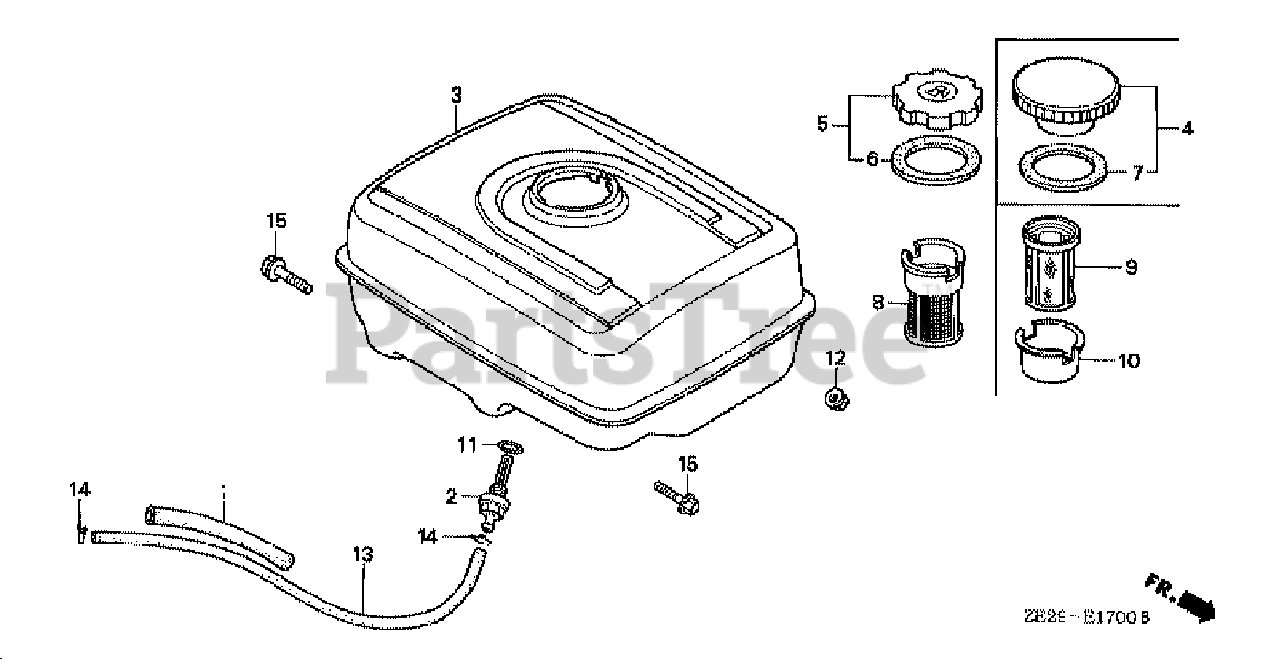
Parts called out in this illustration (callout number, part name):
1	RUBBER, SUPPORTER (107MM)
2	JOINT, FUEL TANK
3	TANK, FUEL *NH31* (MCKINLEY WHITE)
3	TANK, FUEL *NH1* (BLACK)
4	CAP, FUEL FILLER
5	CAP, FUEL FILLER
6	GASKET, FUEL FILLER CAP
7	GASKET, FUEL FILLER CAP
8	FILTER, FUEL
9	FILTER, FUEL
10	HOLDER, FUEL FILTER
11	O-RING (13.5X1.5) (ARAI)
12	NUT, FLANGE (8MM)
13	BULK HOSE, FUEL (4.5X3000) (4.5X222)
14	CLIP, TUBE (B8)
15	BOLT, FLANGE (8X25)
